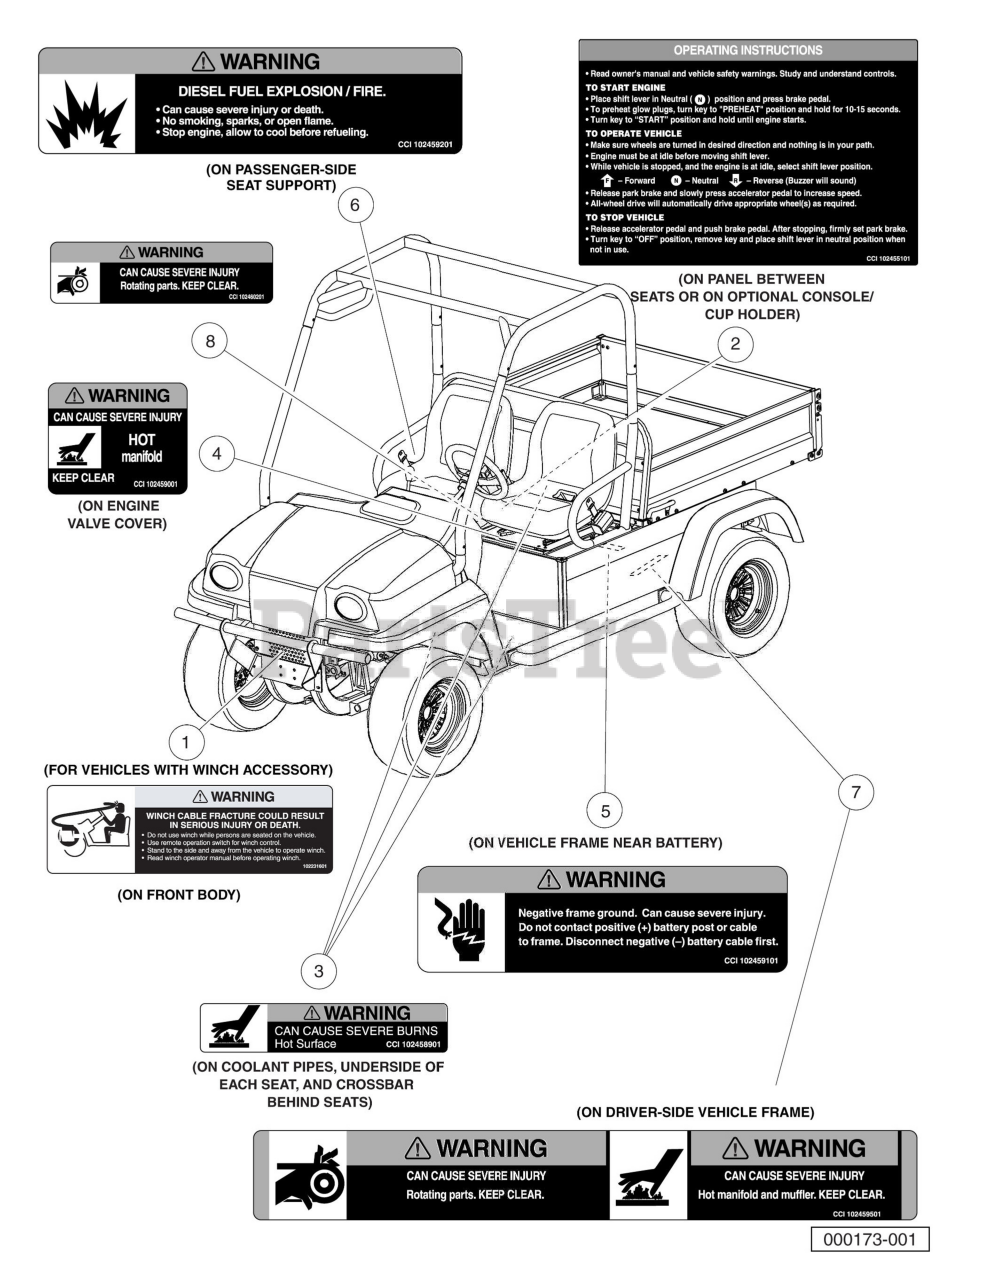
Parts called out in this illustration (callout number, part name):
1	Decal, Winch Cable Fracture Warning
2	Decal, Operating Instructions, Diesel
3	Decal, Hot Surface Warning
4	Decal, Hot Manifold Warning
5	Decal, Frame Ground Warning
6	Decal, Diesel Explosion/Fire Warning
7	Decal, Rotating Parts and Hot Exhaust Warning
8	Decal, Rotating Parts Warning
